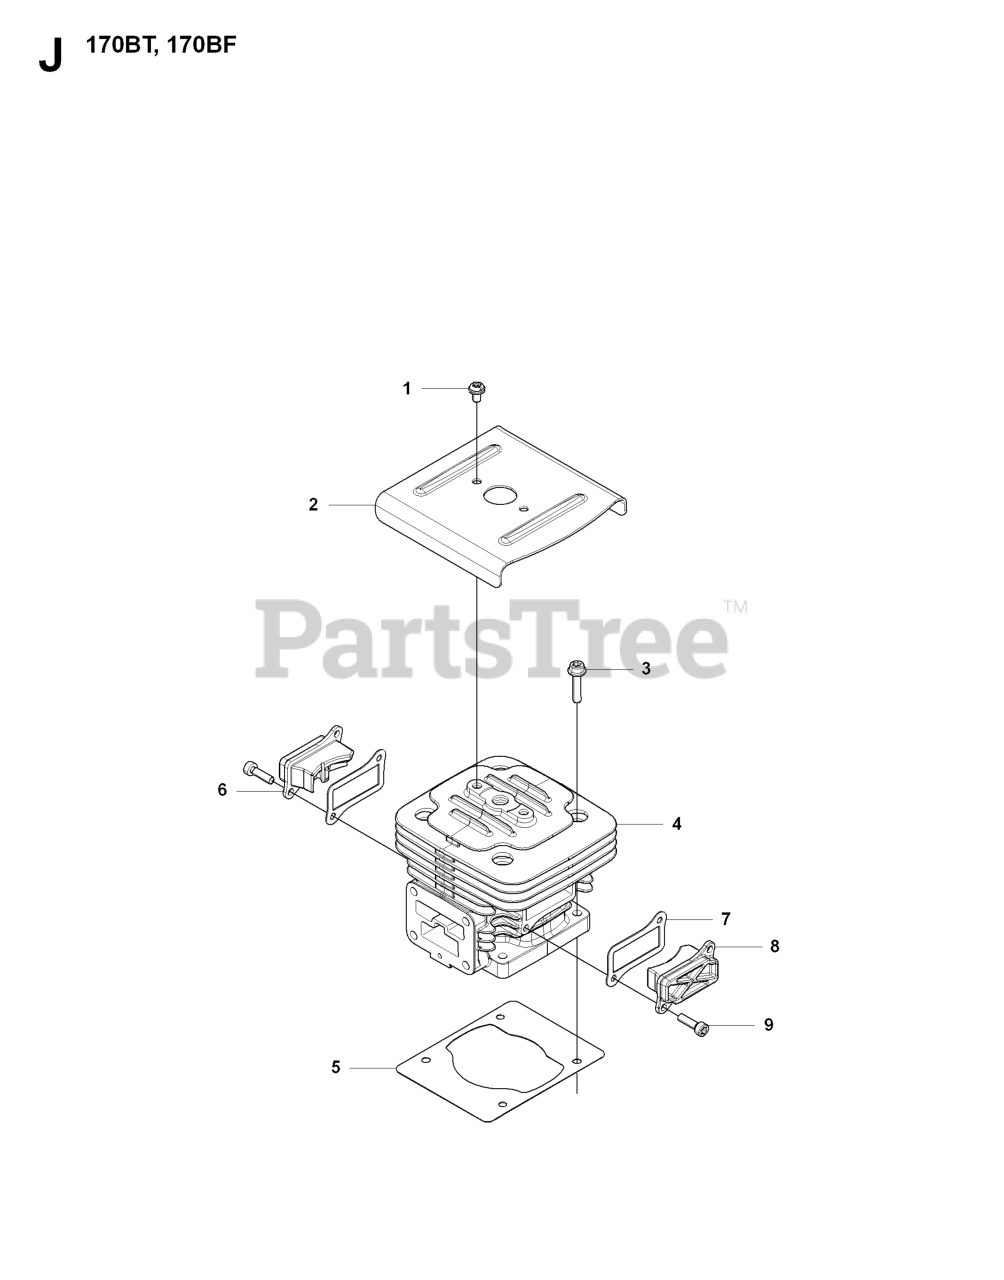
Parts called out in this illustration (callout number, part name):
3	BOLT 22MM
6	COVER,TR-F
8	COVER,TR-S
